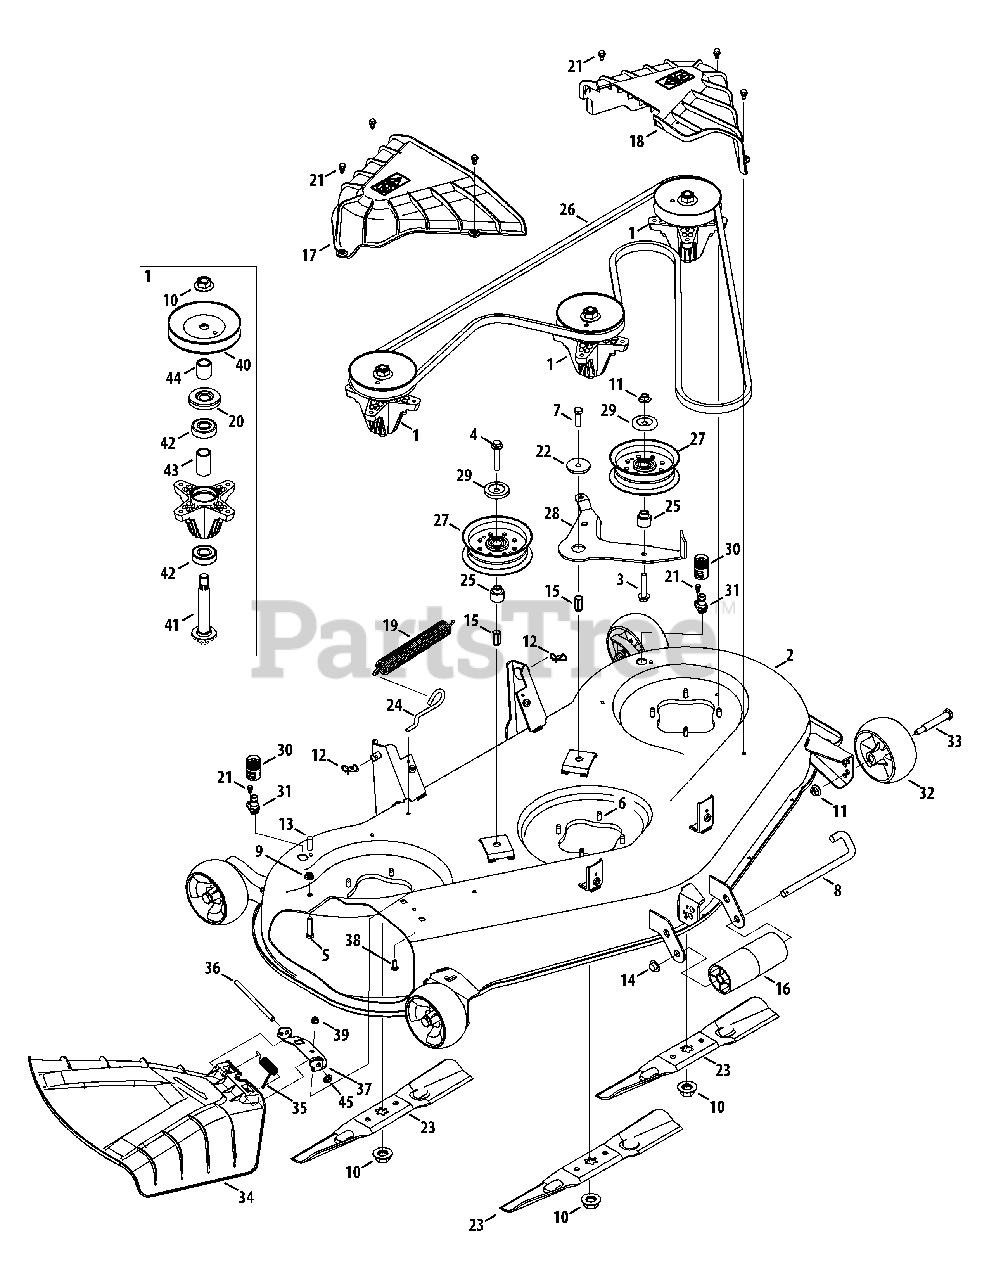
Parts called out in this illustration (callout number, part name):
1	Spindle Ass’y, Pulley, 5.37 Dia
2	Deck, 50"
3	Hex Cap Screw, 3/8-16 x 2.00
4	Hex Cap Screw, 3/8-16 x 2.25
5	Hex Cap Screw, 5/16-18 x 1.50
6	Screw, Self-tapping, 5/16-18, 0.750,
7	Hex Cap Screw, 3/8-16 x 1.25
8	Roller Pin, 1/2 x 7.31 Lg
9	Nut, Flange Lock, 5/16-18, Nylon
10	Nut, Flange, 5/8-18
11	Flange Lock Nut, 3/8-16
12	Bow-Tie Cotter Pin
13	Vinyl Cap, .29 x 1.00
14	Push Cap, 1/2"
15	Rivet Nut, 3/8-16
16	Front Roller
17	Belt Cover, RH
18	Belt Cover, LH
19	Spring, Extension, 1.25 OD x 8.5
20	Bearing Shield
21	Shoulder Screw, 1/4-20 x 0.50
22	Shoulder Spacer, .970 x .190
23	Blade, Cut, 17.27" 2-In-1
24	Deck Spring Rod
25	Shoulder Spacer
26	Belt, V-Type, B Sec x 134
27	Pulley, Idler, 4.50" Dia.
29	Pulley Cap
30	Coupler, Water
31	Deck Wash Nozzle
32	Wheel, Deck, 5.0 Dia. Ball
33	Bolt, Shoulder, .496 x 2.50, 3/8-16
34	Chute Deflector Assembly
35	Spring, Torsion, .440 ID x 1.75
36	Hinge Pin
38	Hex Cap Screw, 1/4-20 x .62
39	Nut, Flange Lock, 1/4-20, Nylon
40	Pulley, Deck, 5.00 Dia.
41	Shaft, Spindle, 5.50
42	Bearing, Ball, .787id x 1.85 Od x .551
43	Spacer, .792 x 1.060 x 1.860
44	Spacer, .792 x 1.060 x 1.191
45	Push Cap
